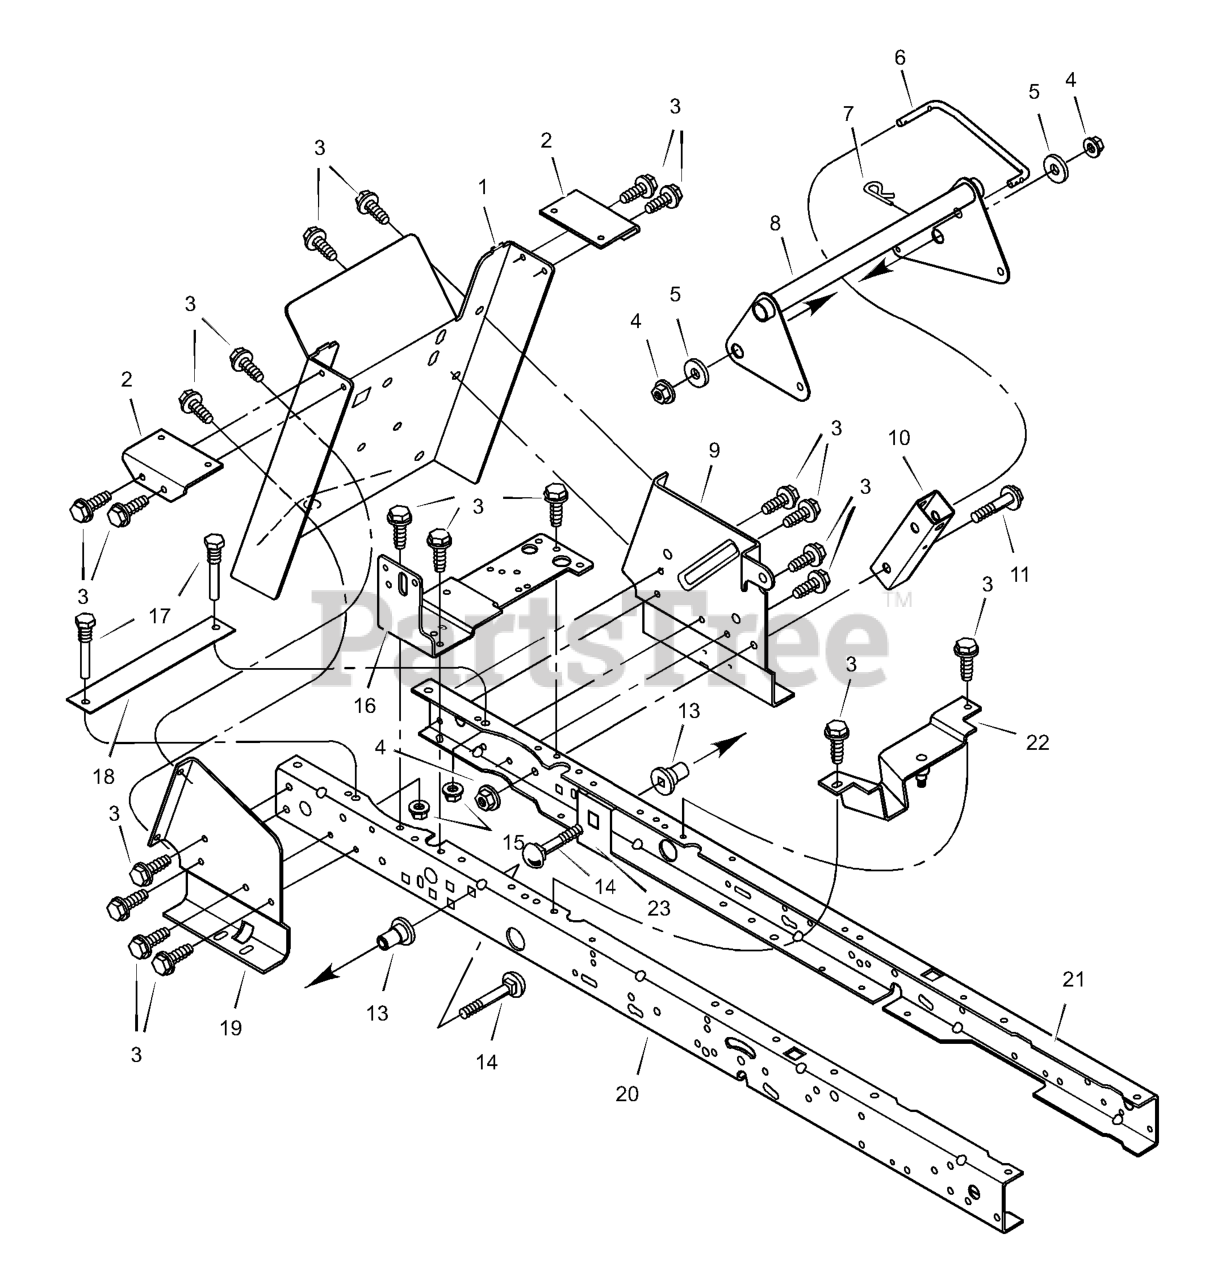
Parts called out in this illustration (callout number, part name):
1	Frame, Rear Hitch
2	Bracket, Seat Deck
4	Nut, Flange
6	Link, Lift Handle
7	Pin, Hair
8	Assembly, Lifter
9	Bracket, Left Transaxle
10	Bracket, Lift Pivot
11	Bolt, Shoulder
13	Spacer, Lifter
14	Bolt, Carriage
15	Nut, Flange
16	Bracket, Right Shift
17	Screw, Guide
18	Bracket, Battery Support
19	Bracket, Right Transaxle
20	Frame, Right
21	Frame, Left
22	Bracket, Idler
23	Plate, Stiffening
